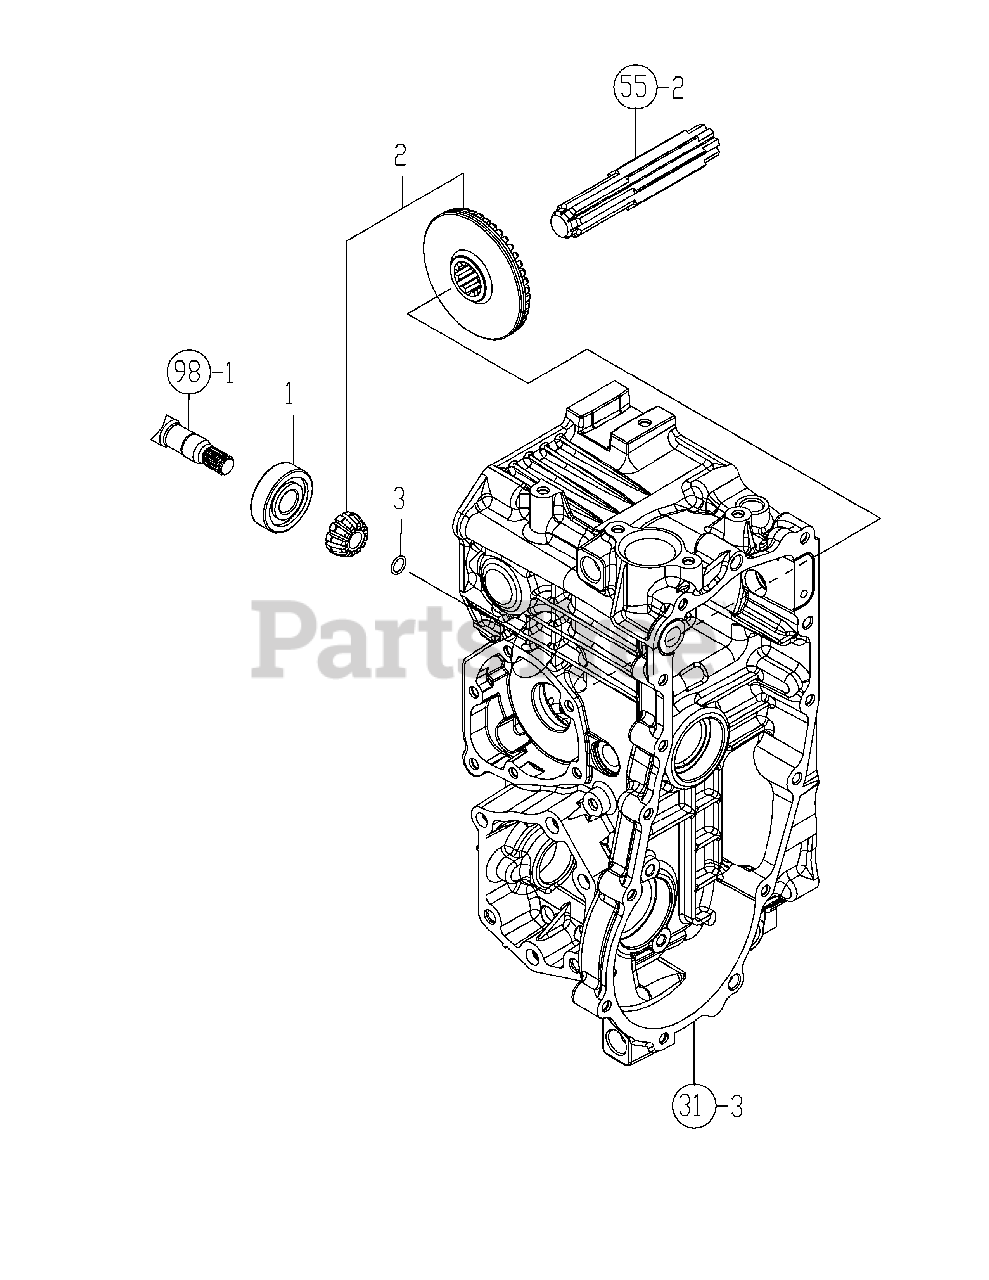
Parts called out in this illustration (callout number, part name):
1	BEARING, 6303RSH2
2	GEAR KIT, INPUT
3	RING, 12 X 1.6
